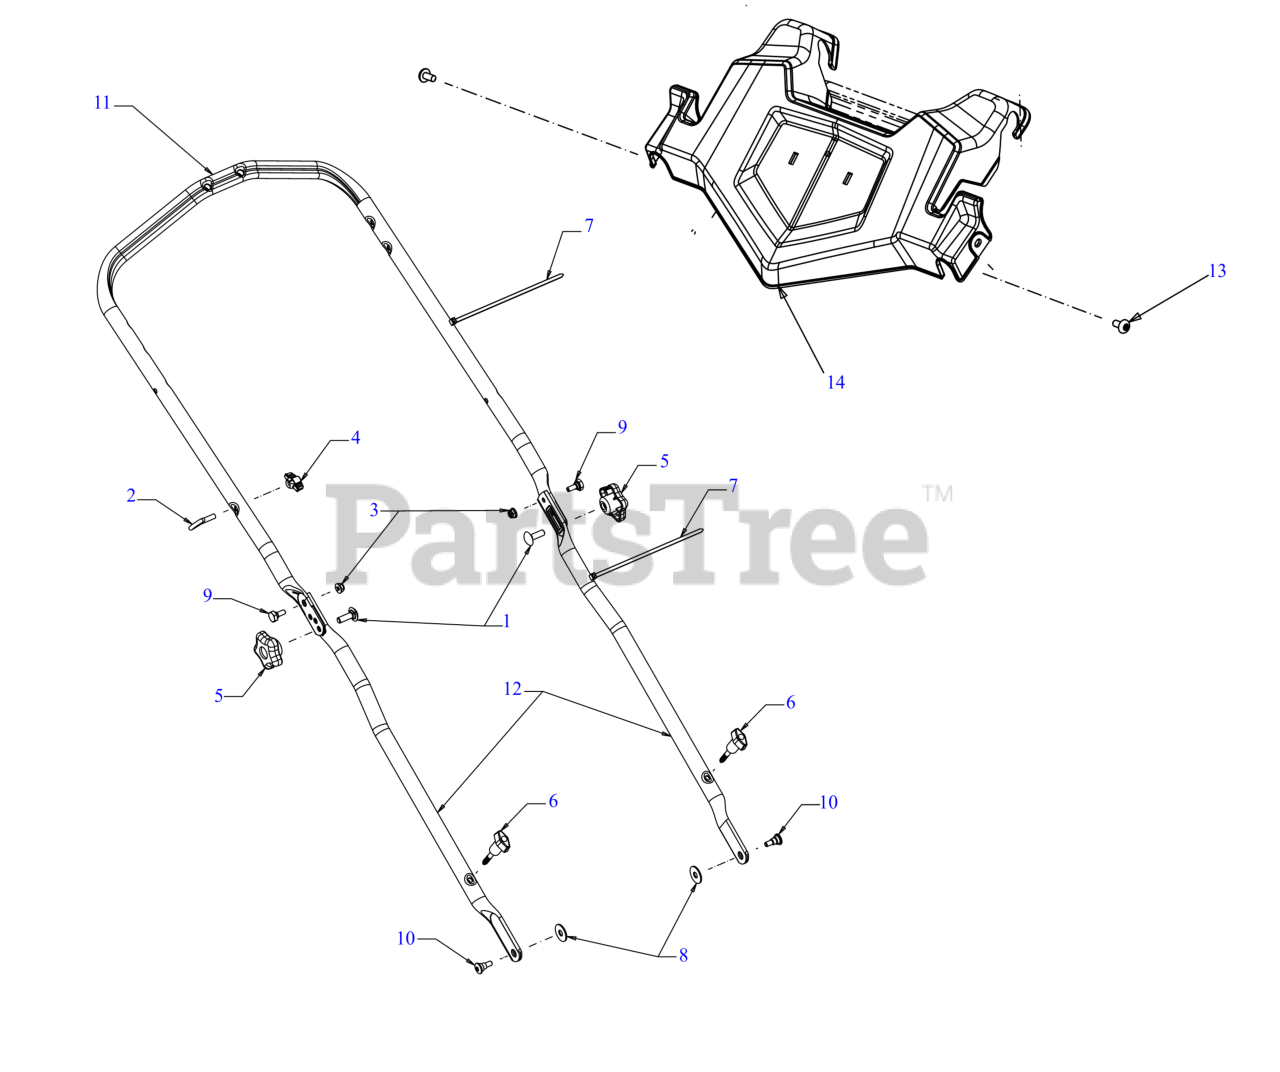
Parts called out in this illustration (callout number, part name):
1	SCREW 5/16-18 x 1.00 GR5
2	EYEBOLT 1/4-20
3	FLANGE LOCK NUT
4	HANDLE KNOB
5	STAR KNOB 5/16-18
6	WING KNOB 1/4-20
7	7" CABLE TIE
8	FLAT WASHER 344X1.00
9	SHOULDER SCREW
10	SHOULDER SCREW .450X .188X 1/4-20
11	UPPER HANDLE
12	LOWER HANDLE (EZ FOLD)
13	SCREW 1/4-14 x .625
14	HANDLE CONSOLE
